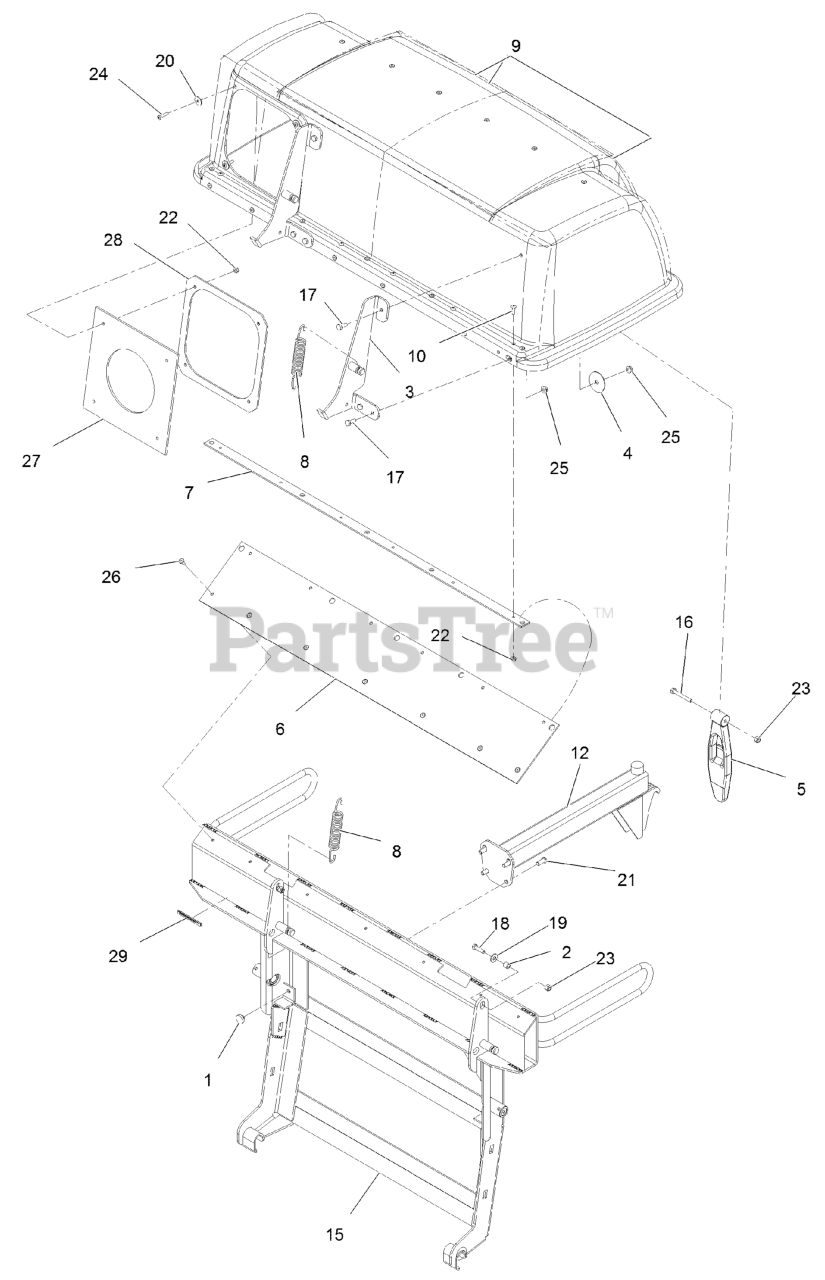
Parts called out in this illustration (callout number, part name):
3	HINGE ASM
7	PLATE-BACKING
8	SPRING-EXTENSION
9	ASM, HOOD
10	SCREW-HEAD, TRUSS
12	BAG SUPPORT ASM
15	FRAME-BAG, TWIN
16	SCREW-HH
17	SCREW-HH
18	SCREW-HH
19	WASHER-FLAT
20	WASHER-FLAT
21	SCREW-HSBH
22	NUT-LOCK, NI
23	NUT-LOCK, NI
24	SCREW-PPH
26	RIVET-BLIND
27	SEAL-CHUTE
28	CLAMP-SEAL
29	DECAL-WARNING
